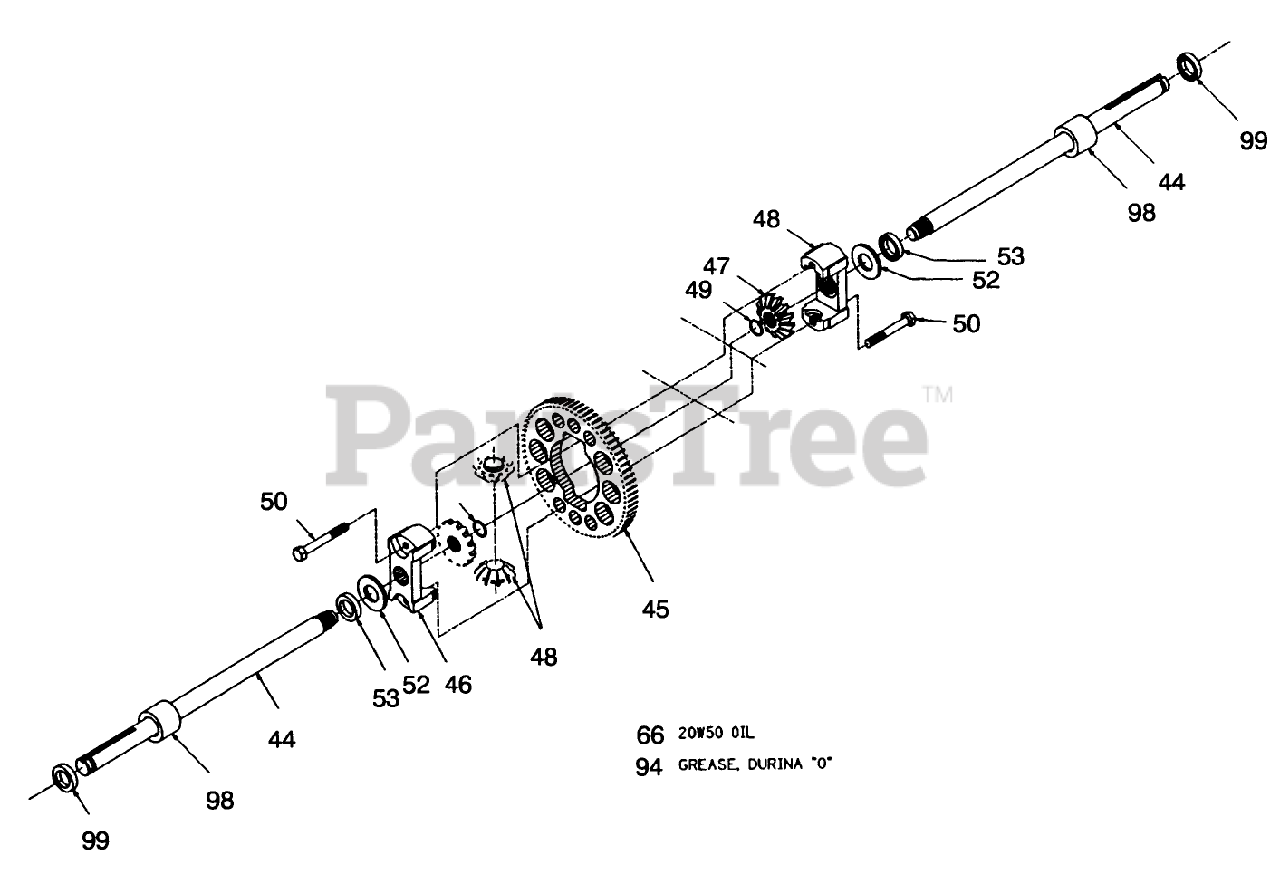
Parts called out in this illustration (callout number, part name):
44	Shaft-Axle
46	Housing-Diff.
50	Bolt-Diff. Locking
52	Washer
53	Seal ASM
94	Grease Durina "O"
98	Sleeve-Bearing
99	Seal-Wiper
